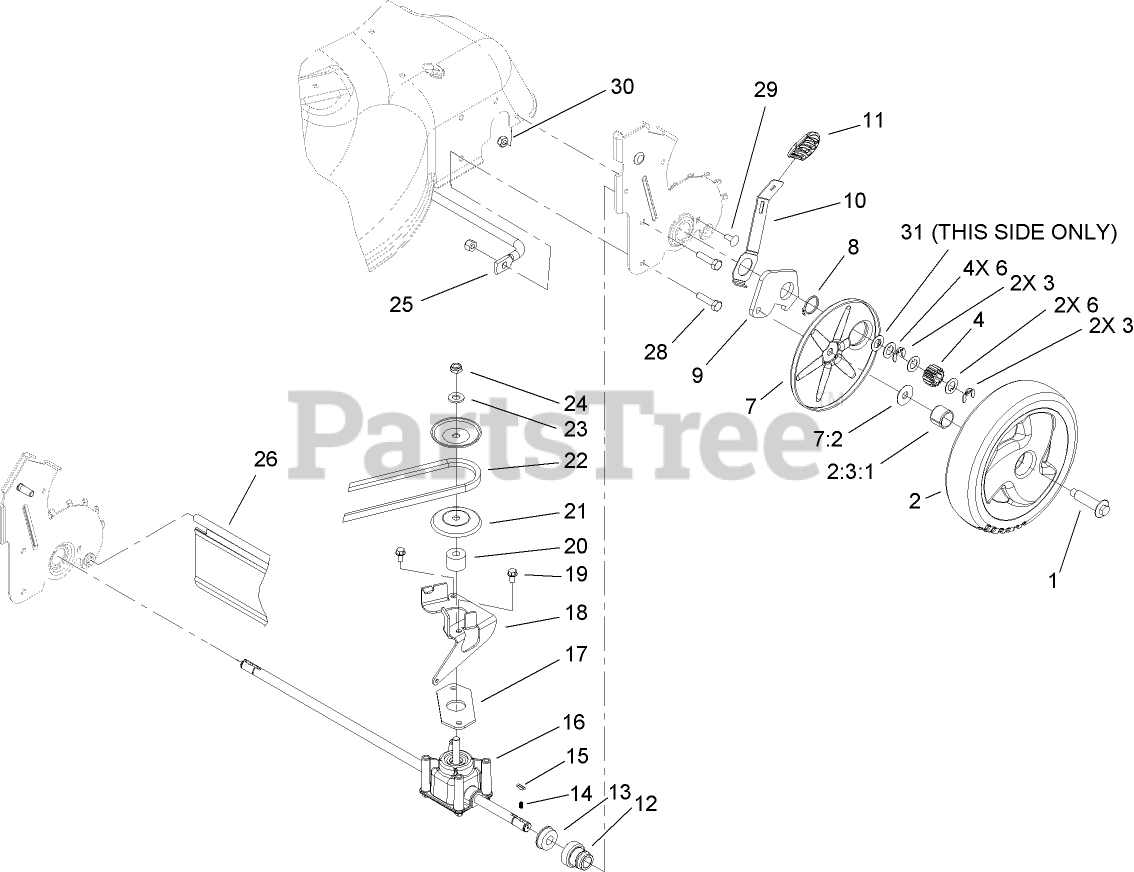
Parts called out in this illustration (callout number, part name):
1	BOLT-SHOULDER
2	WHEEL GEAR ASM
2:3	Wheel ASM
2:3:1	BUSHING
3	RING-RETAINING,CLIP
4	GEAR-PINION, 15T
6	WASHER-THRUST
7:1	Loose Parts Package
7:2	WASHER-STEPPED
8	RING-RETAINING
9	ARM-PIVOT, REAR (LH)
10	ARM-SPRING
11	KNOB-LEVER, HOC
12	RETAINER-BEARING, HOC
13	BEARING-BALL
14	SPRING-COMPRESSION
16	TRANSMISSION ASM
17	GASKET-GEARBOX
18	BRACKET-PIVOT
19	SCREW-HWH
20	SPACER
21	PULLEY-HALF
22	BELT-V
23	WASHER-FLAT
24	NUT-HEX
25	BRACE-PLATE, HOC
28	SCREW-HH
29	SCREW-CARR
30	NUT-LOCK, NI
31	WASHER-PLAIN
